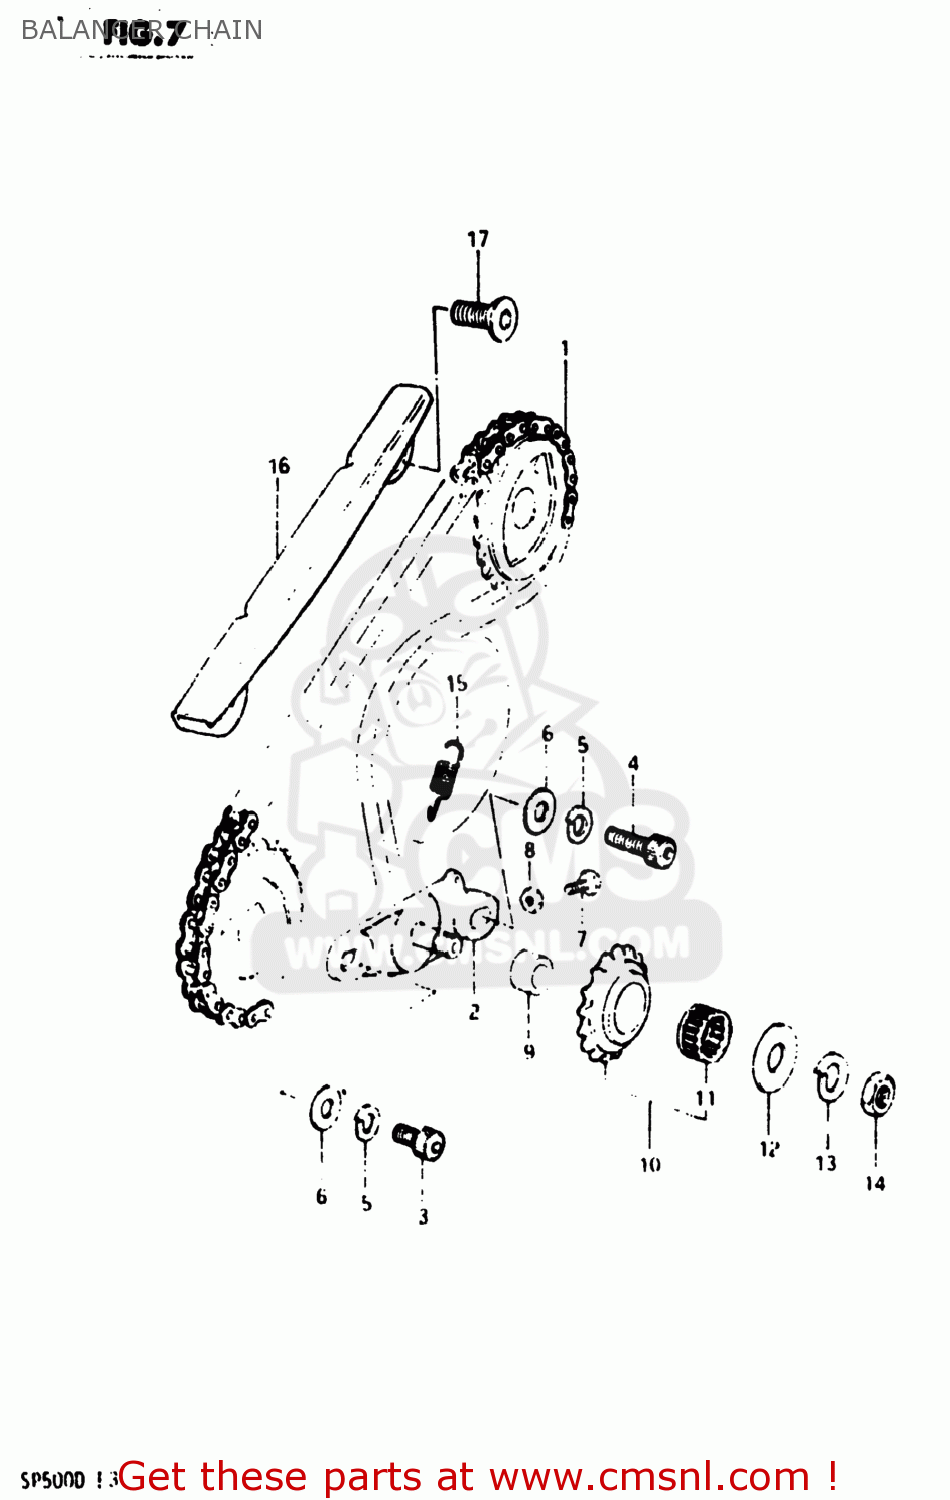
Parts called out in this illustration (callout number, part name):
1	GOVERNOR ASSEMBLY,EXHAUST
2	BRACKET,BALANCER CHAIN TENSIONER
3	BOLT(8X22)
4	BOLT
5	LOCK WASHER
6	WASHER
7	BOLT 5X20
8	NUT
9	SPACER,TENSIONER SPROCKET
10	ROD,EXHAUST VALVE
11	BEARING(17X23X12)
12	WASHER
13	WASHER,LOCK 12
14	NUT
15	SPRING
16	GUIDE,BALANCER CHAIN
17	SCREW
